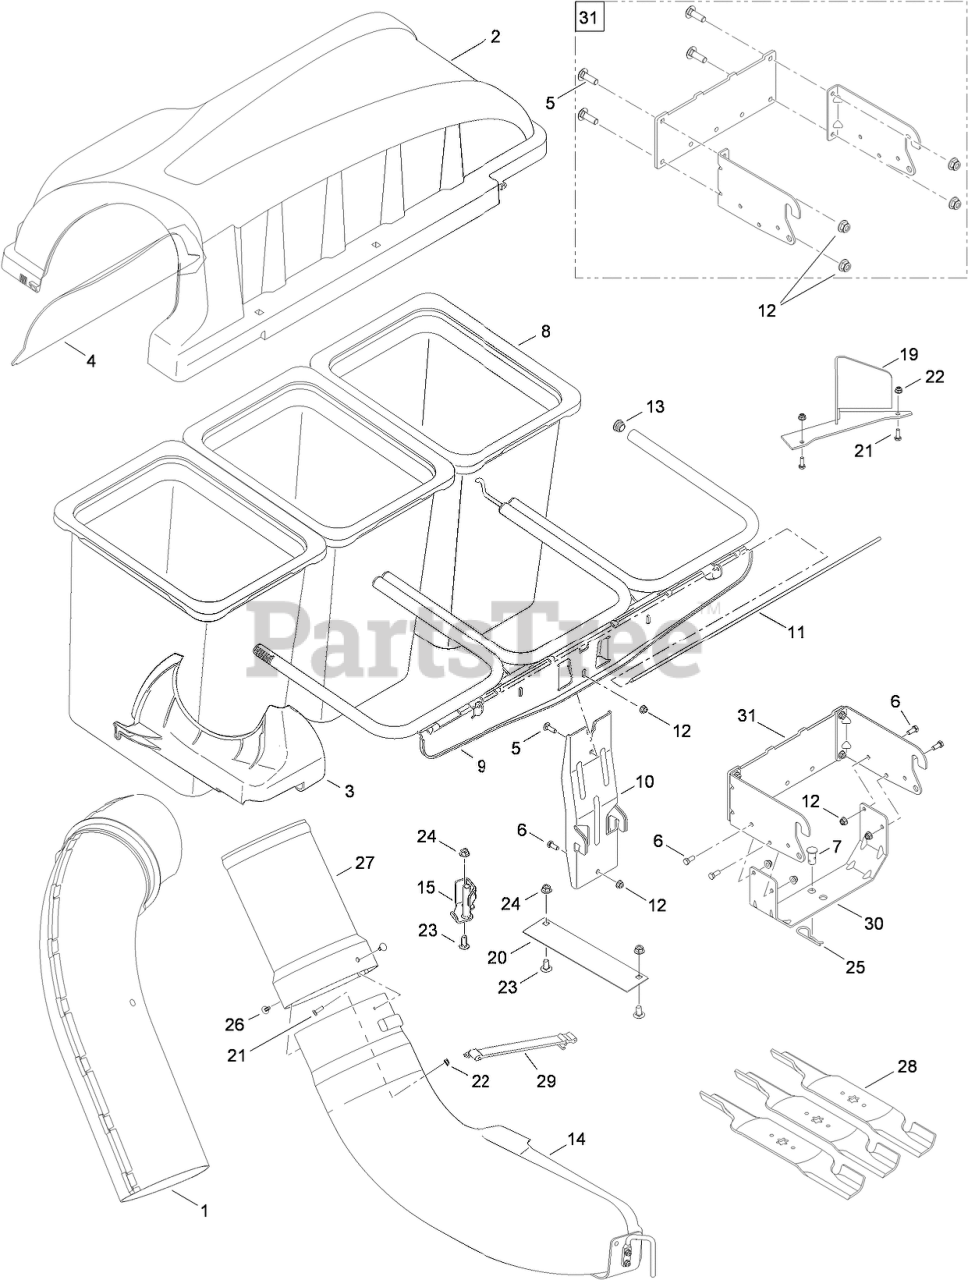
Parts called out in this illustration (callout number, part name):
1	UPPER CHUTE ASM
2	TRIPLE BAGGER COVER ASM
3	SUPPORT-CHUTE, UPPER
4	SCREEN-COVER, BAGGER
5	BOLT-CARR
6	SCREW-HH
7	PIN-CLEVIS
8	GRASS BAG ASM
9	TRIPLE BAG SUPPORT ASM
10	BRACKET-SUPPORT, VERTICAL
11	PIN-HINGE, COVER
12	NUT-LOCK, FLANGE
13	PLUG-END
14	ELBOW-CHUTE, DISCHARGE
15	BRACKET-STOP, CHUTE
19	Baffle-Deck
20	PLATE-CHUTE, DISCHARGE
21	SCREW-HH
22	NUT-LOCK, FLANGE
23	BOLT-CARRIAGE
24	NUT-LOCK, FLANGE
25	CLIP-HAIRPIN
26	CLIP-RATCHET, FASTENER
27	ADAPTER-CHUTE, BAGGER
28	BLADE-BAGGING (STAR, 17.90 INCH)
29	STRAP-CHUTE
30	SUPPORT-BRACKET, UNIVERSAL
31	HITCH BRACKET ASM
